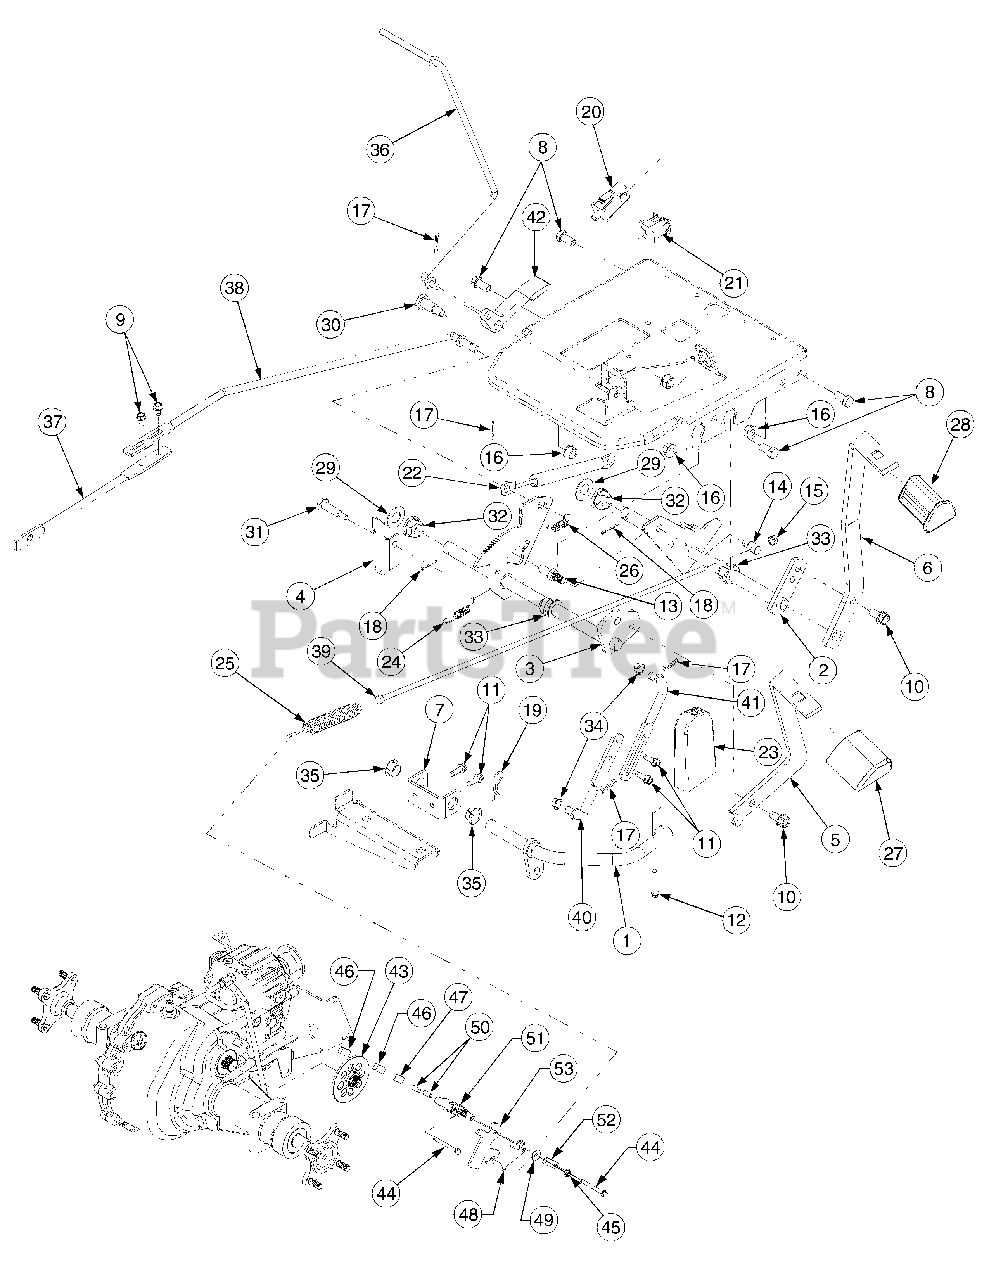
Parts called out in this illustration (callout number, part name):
3	Shaft Assy, Forward/Reverse
8	Screw, Hex Cap, 3/8-16 x .75 GR5
9	Screw, Hex Wash Hd Tapp 1/4-20 x .5
10	Screw, Hex Wash Hd Tapp 3/8-16x .75
11	Screw, Hex Wash Hd Tapp 1/4-20x .75
12	Screw, Truss Mach, #12 x 1.5
13	Pin, 3/8-16 x 1.0
14	Ferrule, Adjustment, 1/4-20 Thrd
15	Nut, Hex Sems, 1/4-20
16	Nut, Hex Flange Lock, 3/8-16
17	Pin, Internal Cotter, 5/16 Dia x 1.12
18	Pin, Cotter, 3/32 x 1.0
19	Pin, Internal Cotter, 3/8 Dia x 1.62
20	Switch, Interlock (Brake)
21	Switch, Snap Mount (Reverse)
22	Cylinder, Damper, .59 OD x 7.84 Lg
23	Pedal, Reverse
24	Spring, Extension, .38 OD x 2.1
25	Spring, Extension
26	Spring, Extension, .375 OD x 1.44
27	Pad, Forward Foot Control
28	Pad, Brake Foot
29	Washer, Flat, .64 x 1.24 x .06 HT
30	Shoulder Bolt, .50 OD x .840
31	Screw, Shoulder, .374 x 1.16
32	Bearing, Hex Flange
33	Bearing, Hex Flange Split
34	Bearing, Flange, .375 x .58 x .25
35	Bearing, Flange, .625 x .938 x .344
36	Rod, Cruise
37	Rod, Rear F/R Control
38	Rod, Front F/R Control
39	Rod, Brake
40	Rod, Rear Connecting
41	Rod, Front Connecting
42	Latch, Cruise
43	Disc, Brake
44	Screw, Hex Wash Hd, Tapp, 1/4-20 x 2.375
45	Nut, Hex Nylon Lock, 5/16-24
46	Pad, Brake
47	Plate, Puck
48	Spring, Torsion
49	Washer, Flat, .343 x .88 x .062
50	Pin, Brake Actuating
51	Yoke, Brake
52	Bracket, Brake Anti Rotation
53	Arm, Brake Actuator
